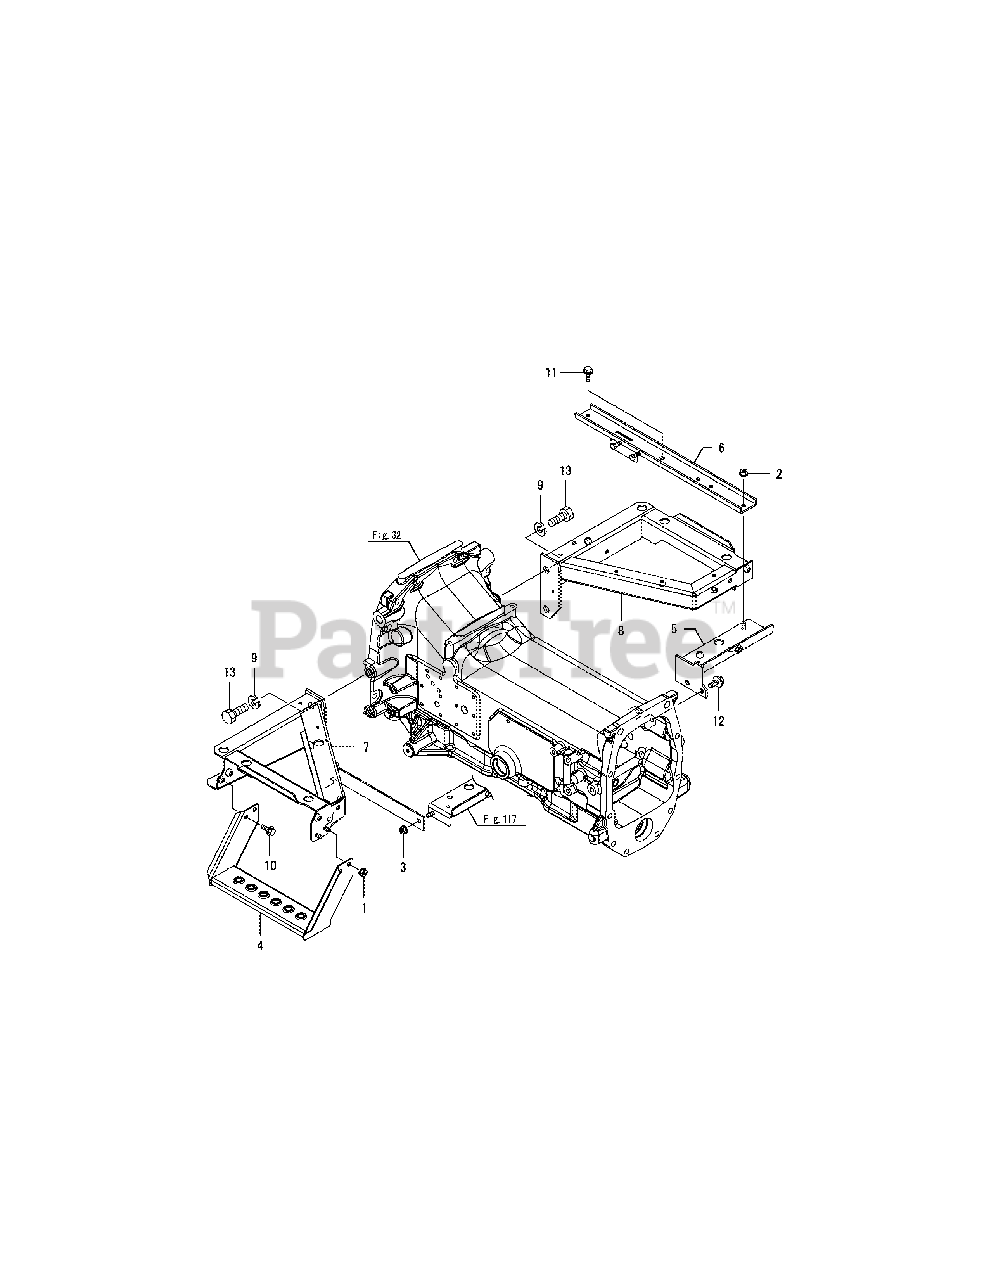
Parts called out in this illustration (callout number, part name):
1	NUT W/WASHER 8
2	NUT W/WASHER 8
3	NUT W/WASHER 8
4	SUB-STEP ASSY,
5	SUPPORT ASSY, REAR R
6	SUPPORT ASSY, SCV
7	SUPPORT,FRONT L ASSY
8	SUPPORT,FRONT R ASSY
9	SPRING WASHER 16
10	BOLT M 8X 16 PLATED
11	BOLT M 8X 16 PLATED
12	BOLT M10X 20 PLATED
13	BOLT M16X 40 PLATED
